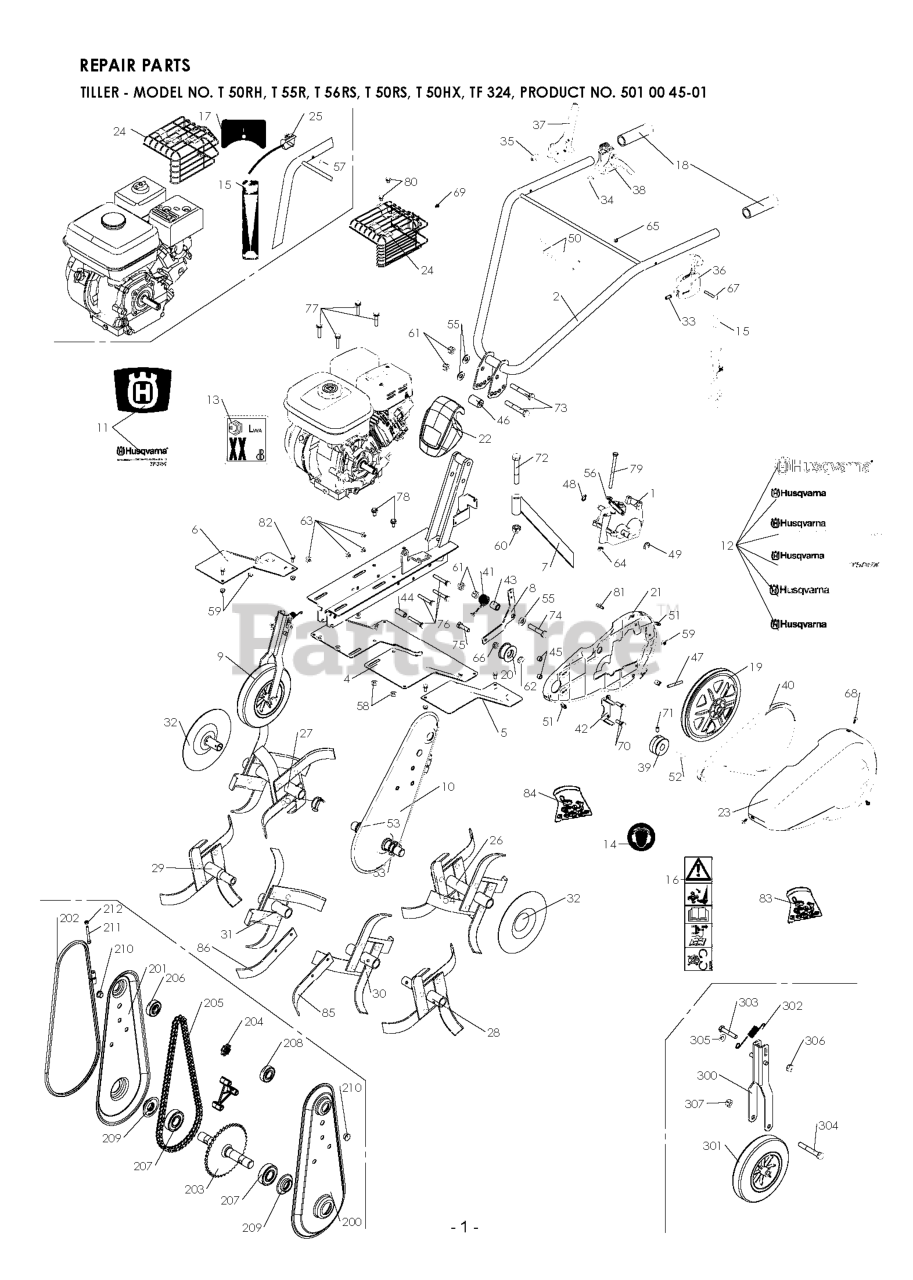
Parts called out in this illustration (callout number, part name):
2	HANDLEBAR PUBERT 3002070602
3	CHASSIS PUBERT 3002070601
8	ARM
22	COVER HANDLE BAR
33	THROTTLE CABLE
49	RETAINER RING
65	Blocking nut M 6 Z
212	Blocking nut M 6 Z
